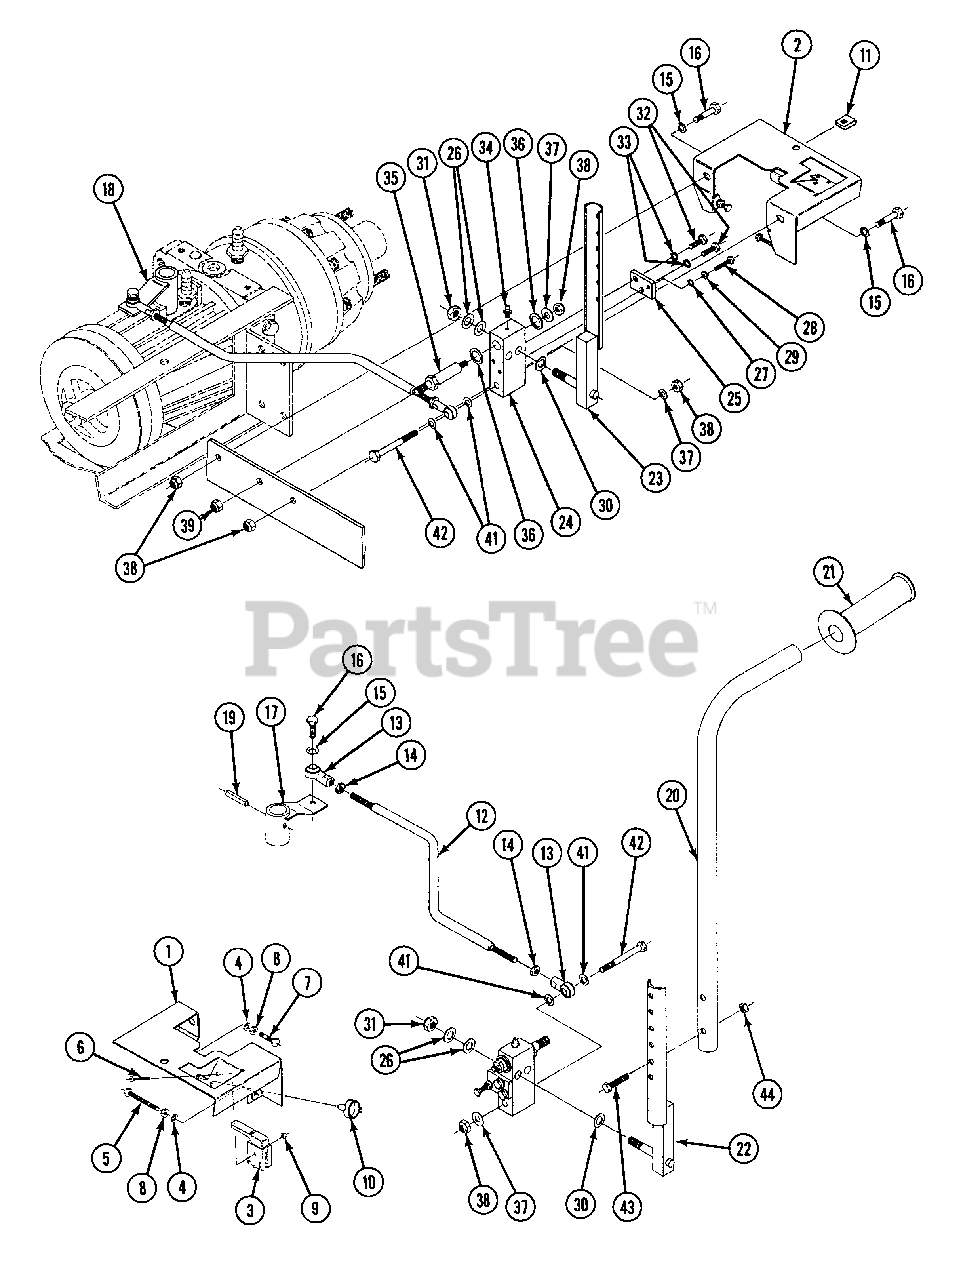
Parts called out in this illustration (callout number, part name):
1	SHIFT ARM BRACKET, RH
2	SHIFT ARM BRACKET, LH
3	SWITCH, NEUTRAL
4	LOCKWASHER, SPLT SPRNG: 1/4
5	CAPSCREW, HS HD: 1/4-20 X 2 GR 5
6	SCREW, RD HD: 10-32 X 1-1/8
7	CAPSCREW, HX HD: 1/4-20 X 1 GR 5
8	NUT, HEX: 1/4-20
9	LOCKNUT, NYLOCK: 10-32
10	CLIP, ROSEBUD: 1/2
11	J-NUT: 5/16-18
12	LINKAGE ROD
13	BALL JOINT, 3/8-24 PLAIN FEMALE
14	NUT, HEX: 3/8-24
15	LOCKWASHER, SPLT SPRNG: 3/8
16	CAPSCREW, HX HD: 3/8-16 X 1 GR 5
17	SHIFT BLOCK WELDMENT, RH
18	SHIFT BLOCK WELDMENT, LH
19	ROLL PIN: 5/16 X 1-1/2
20	UPPER CONTROL LEVER
21	GRIP, HANDLE
22	LOWER HANDLE WELDMENT, RH
23	LOWER HANDLE WELDMENT, LH
24	ROTARY BLOCK
25	ARM STOP
26	WASHER, TYPE B: 1/2
27	LOCKWASHER, SPLT SPRNG: 1/4
28	CAPSCREW, HX HD: 1/4-20 X 1 GR 5
29	NUT, HEX: 1/4-20
30	D-WASHER
31	LOCKNUT, NYLOCK: 1/2-13
32	CAPSCREW, HX HD: 5/16-24 X 3/4 GR 5
33	LOCKWASHER, SPLT SPRNG: 5/16
34	GREASE FITTING
35	SHOULDER BOLT
36	WASHER, 1/16 THICK: 5/8 ID X 1 OD
37	FLAT WASHER: 3/8
38	LOCKNUT, NYLOCK: 3/8-16
39	LOCKNUT, NYLOCK: 1/2-13
41	FLAT WASHER: 5/16
42	CAPSCREW, HX HD: 3/8-16 X 2-3/4 GR 5
43	CAPSCREW, HX HD: 5/16-18 X 1-3/4 GR 5
44	LOCKNUT, NYLOCK: 5/16-18
